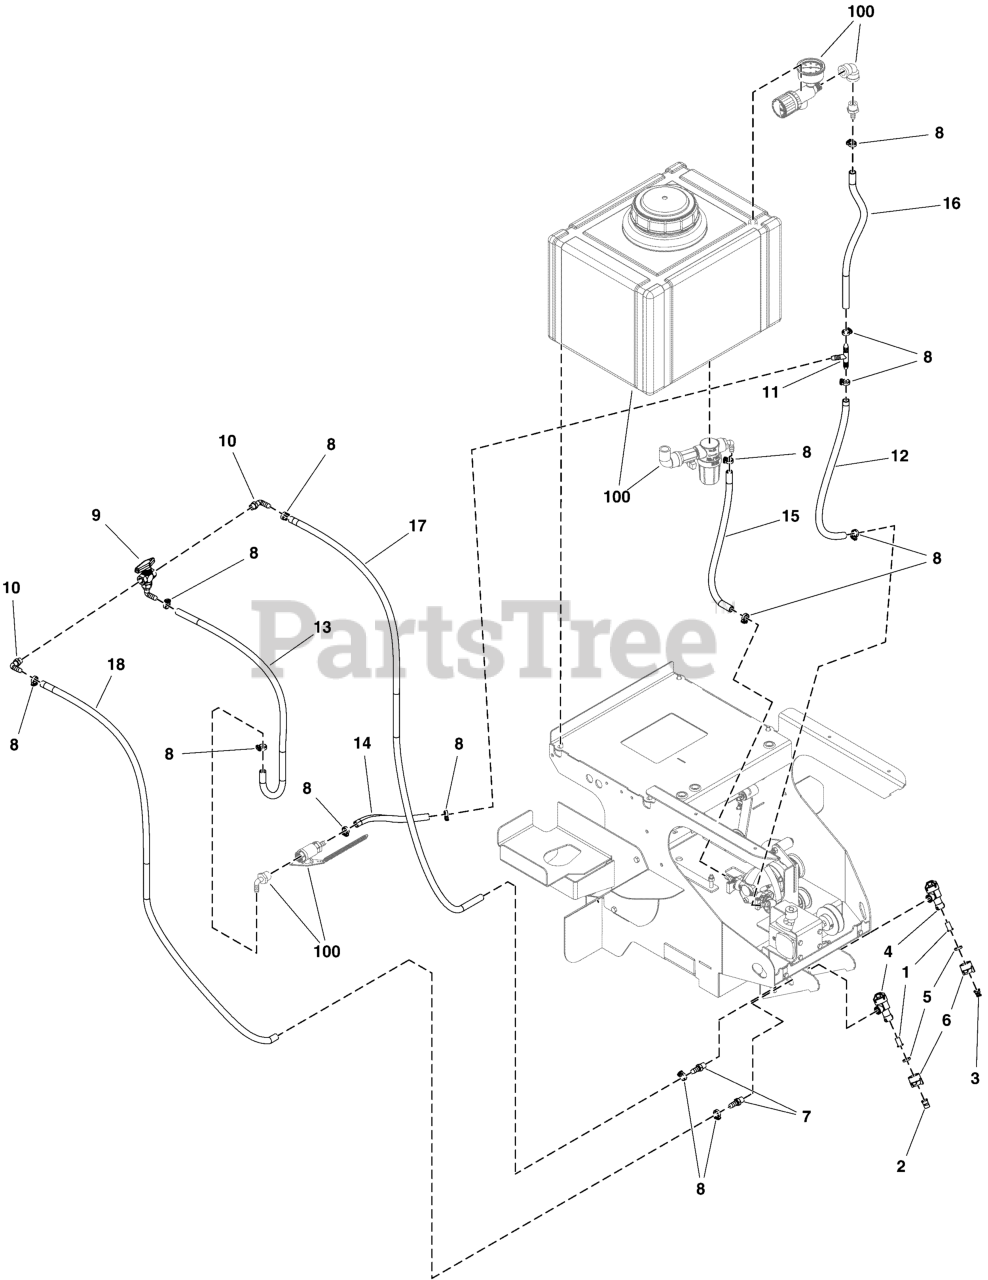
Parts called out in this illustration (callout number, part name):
1	STRAINER, 50 MESH, POLYPROPYLENE TIP
2	NOZZLE, TURBO FLOODJET BROADCAST, TK-VS5
3	NOZZLE, TURBO TRIM, TT11004VP
4	NOZZLE BODY ADAPTER
5	NOZZLE CAP SEAT GASKET, STANDARD
6	QUICK ATTACH CAP, STANDARD
7	FITTING, 1/4 MALE, 3/8 BARB
8	CLAMP, MINIATURE WORM GEAR MAH6
9	VALVE, 1/2FNPT, 3-WAY
10	FITTING, 1/4NPT - 3/8 BARB, 90 ELBOW
11	FITTING, TEE 3/8 BARB
12	HOSE, .375 ID, 18" LONG
13	HOSE, SPRAY CONTROL, .375 ID, 32" LONG
14	HOSE, .375 ID, 8" LONG
15	HOSE, .375 ID, 13" LONG
16	HOSE, .375 ID, 16" LONG
17	HOSE, NARROW SPRAY, .375 ID, 51" LONG
18	HOSE, WIDE SPRAY, .375 ID, 49" LONG
19	HOSE, .375 ID, 15" LONG
100	Refer to: Tank Spray Group
